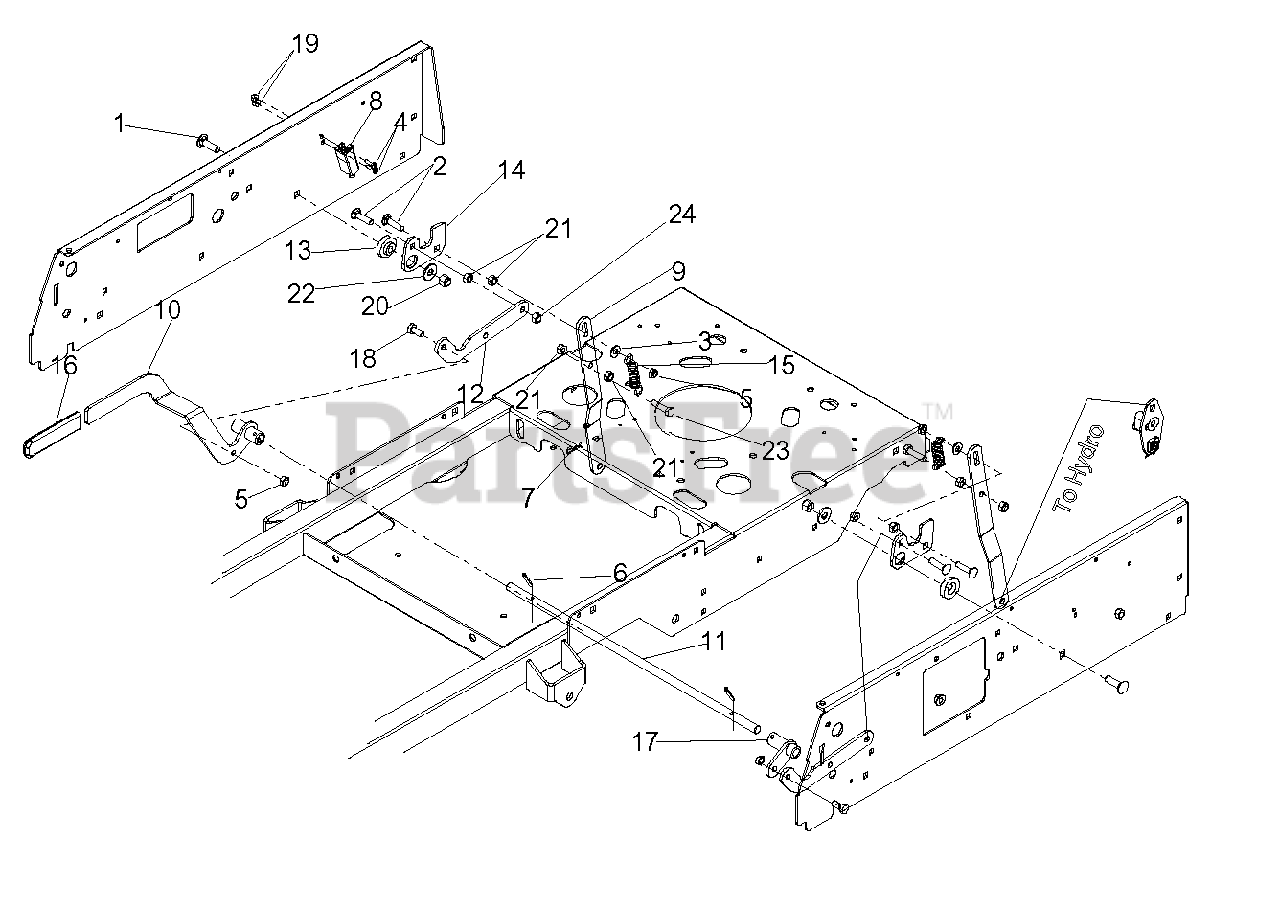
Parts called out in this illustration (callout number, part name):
1	RHSNB 3/8-16 X 1-1/4
2	BOLT, CARRIAGE 5/16X1-1/4
3	5/16STD FL WASH TYPA
4	SCREW #10-24 X 5/8
5	5/16-18 THIN PROF NY
6	ROLL PIN 3/16 X 1-1/4
7	COTTER HP .08 DIA X 1.19
8	SWITCH, INTERLOCK
9	LWR BRAKE LINK
10	BRAKE HANDLE DRILLED
11	BRAKE ROD
12	UPPER BRAKE LINK
13	BRAKE ARM PIVOT
14	BRAKE PIVOT
16	GRIP BRAKE HANDLE
17	BRAKE ARM DRILLED BLK
18	HCS 5/16C X 3/4
19	NUT 10-24 NYLOC
20	NUT 3/8-16 NYLOC
21	NUT 5/16C HEX
22	WASHER 3/8 FLAT
23	HCS 5/16C X 1 1/4
24	NUT 5/16 NYLOC
